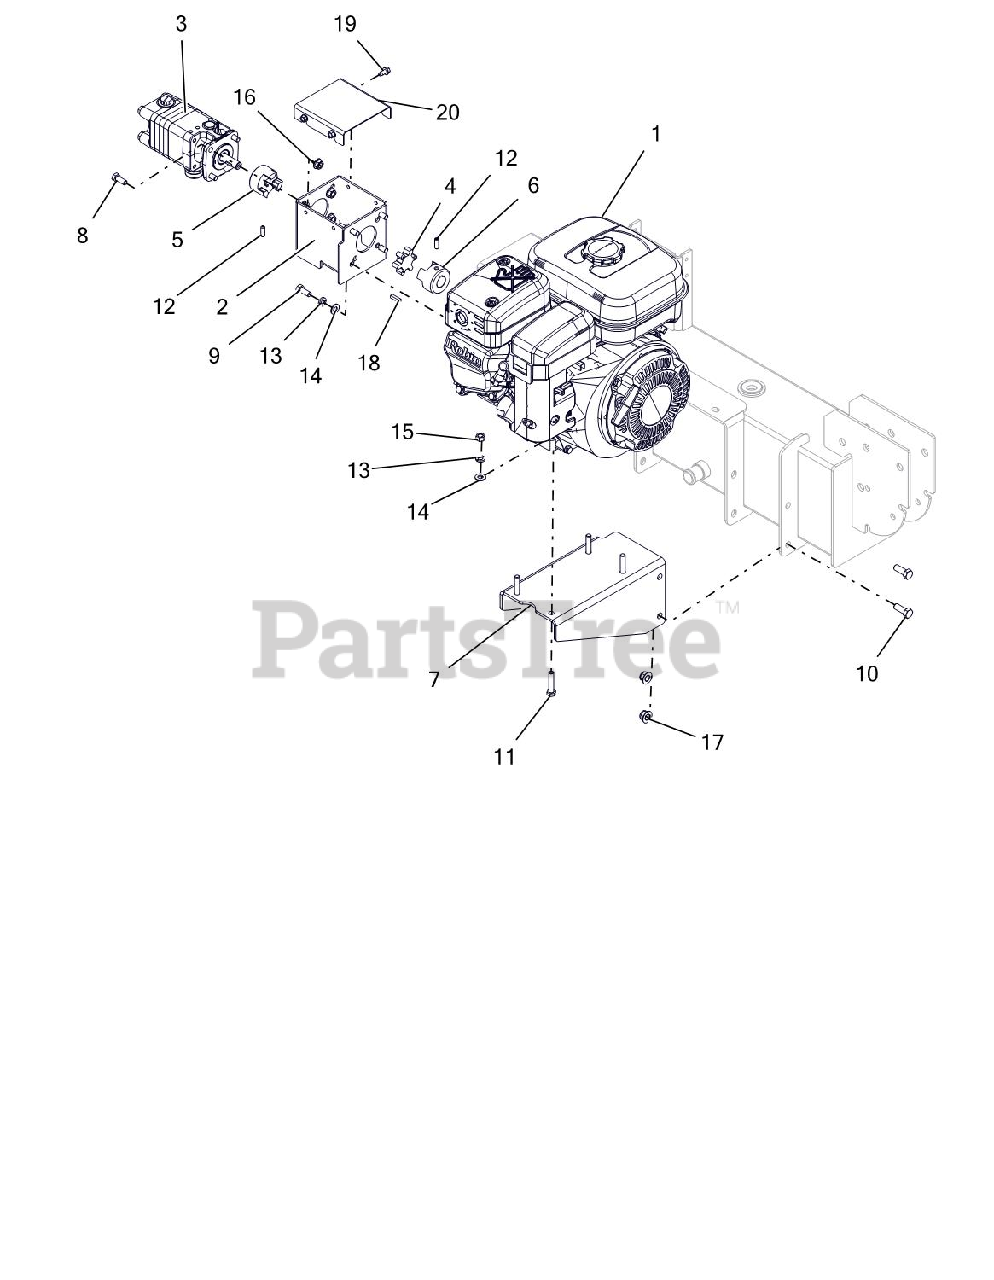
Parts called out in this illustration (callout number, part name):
1	ENGINE,SUBARU EX210DT1032-MP
2	WLDMT, PUMP MOUNT BRKT
3	PUMP,SPLITTER-13 GPM
4	SPIDER - URETHANE
5	COUPLER - DRIVE 1/2"
6	COUPLER - DRIVE, 3/4"
7	MOUNT-ENGINE
8	@BLT-HEX .31-18X.75 GR5 YWZC
9	BLT-HEX .31-24X.75 YWZC GR5
10	@BLT-HEX .38-16X1.00 GR5 YWZC
11	@BLT-HEX .31-18X1.50 GR5 YWZC
12	SCR,SET .25-20X.75 PCPT SH
13	WSHR-LK .312X.097 HVY YWZC
14	@WSHR-FL-STL.344X.688X.065YWZC
15	@NUT-HEX .31-18 YWZC
16	@NUT-LK-TOP-FLG .31-18 YWZC
17	@NUT-LK-NYL-FLG .38-16 YWZC
18	KEY-SQ .188X.75X.188
19	SCR-TAP .25-20X.50 HWH TR YWZ
20	COVER W/DECALS
